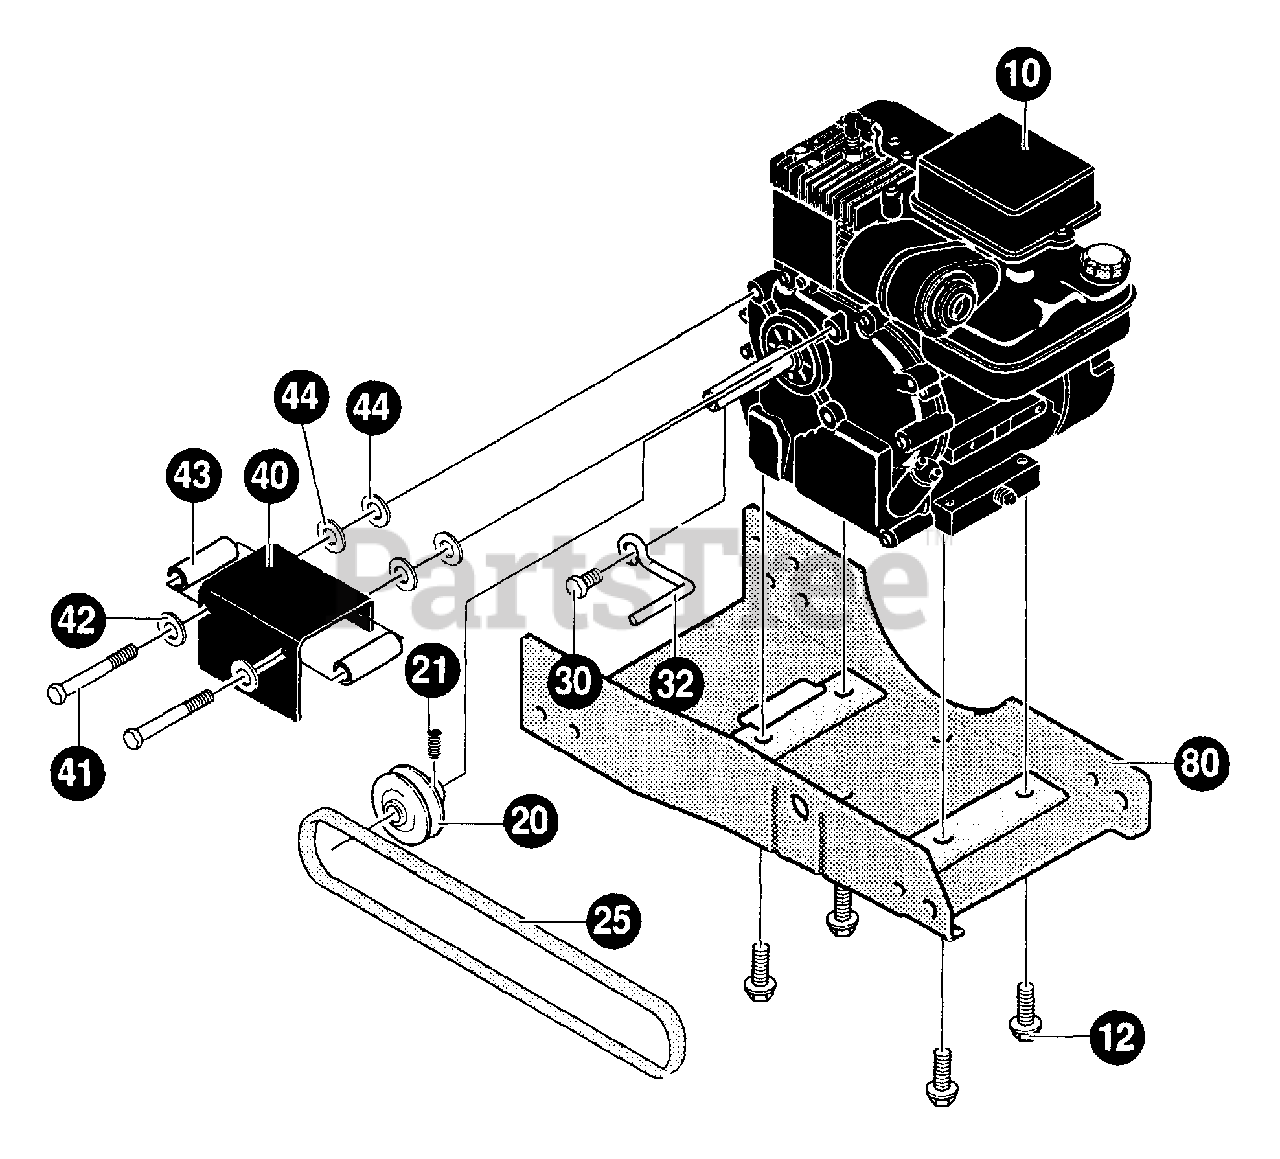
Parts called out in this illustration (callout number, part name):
10	ENGINE
12	SCREW, 3/8-16X1.00
20	PULLEY, ENGINE
21	SCREW, 5/16-18X.25 ALHSETCPPL
25	BELT, V 4L 32.60LG
30	SCREW AND WASHER ASSEMBLY
32	GUIDE, BELT
40	COVER, ENGINE PULLEY
41	SCREW, 5/16-24X3.00 IN.
42	FLATWASHER, .344X.69X.065
43	SPACER, SLEV .335X.43X2.37
44	WASHER, FLAT .344X.69X.065
80	FRAME, EDGER
